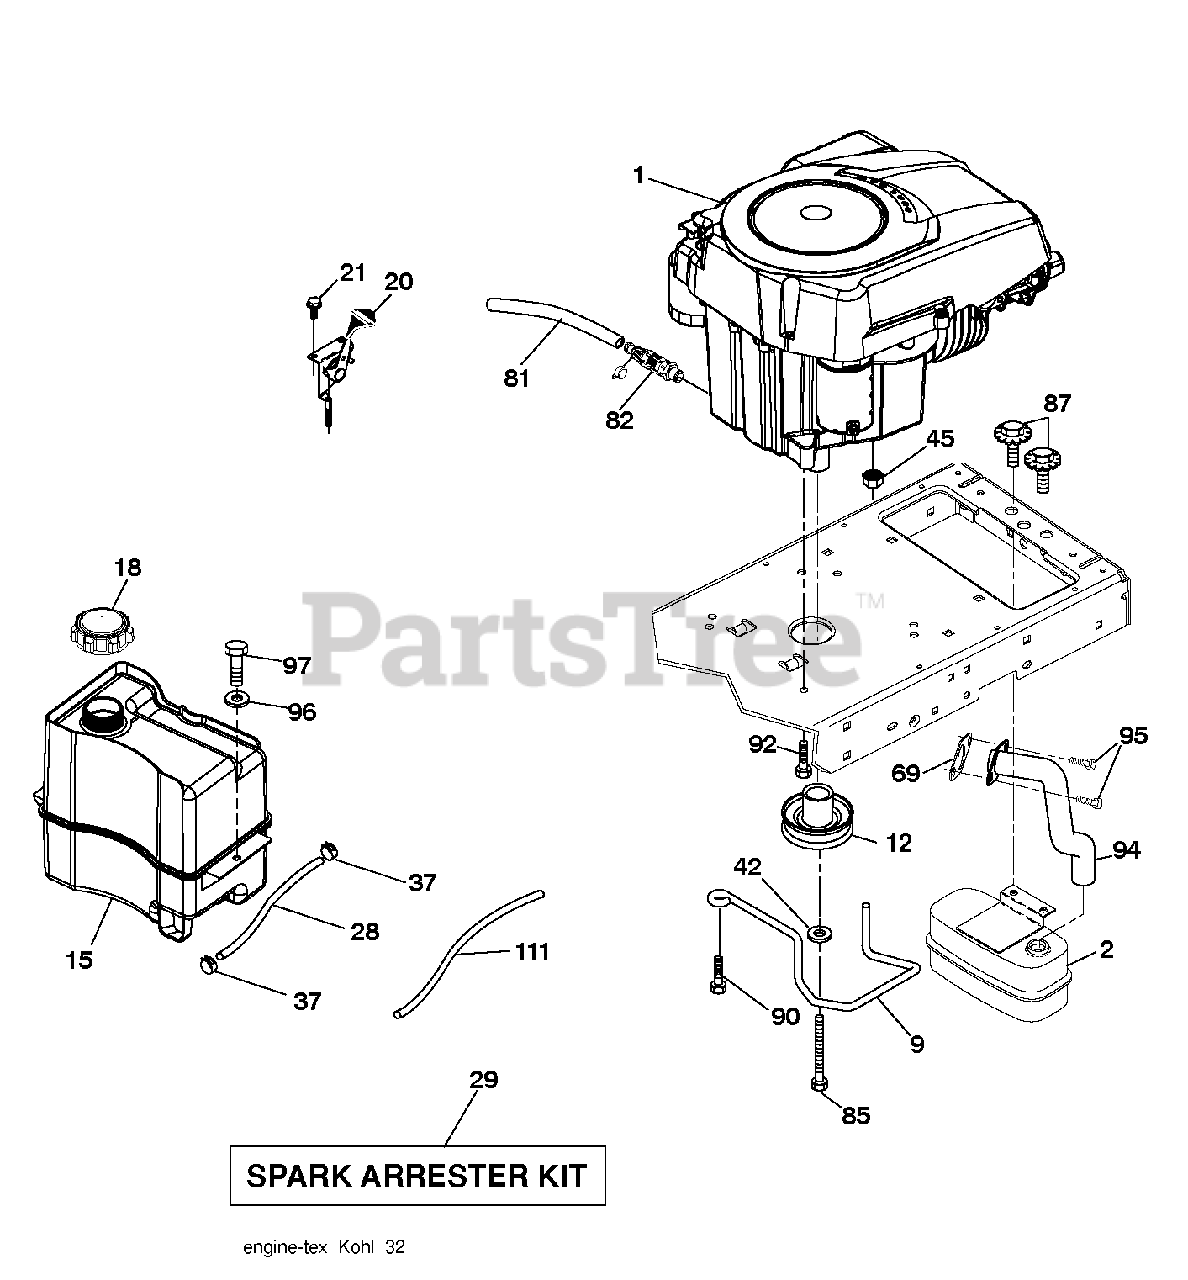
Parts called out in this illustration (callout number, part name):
1	Husqvarna TBD
2	MUFFLER.SINGLE.CYL.KOHL/B&S
9	KEEPER.BELT.ENGINE.4.2
12	PULLEY ENGINE
15	TANK.ASM.FRT.2.5 GAL.W/CAP.EPA
18	CAP.2.25'.VENTED.TETHER .EPA
20	CONTROL.TH/CK.COBRA.KO
21	SCREW.#10 X 0.750.BOS
28	LINE.FUEL.20"FRONT.EMI
29	KIT.SPARK ARRESTOR 794945 B&S
37	HOSE CLAMP
42	LOCKWASHER
45	NUT
69	GASKET.EXHAUST.KOHLER
81	TUBE, DRAIN OIL ASM.
82	VALUE.OIL.DRAIN
85	BOLT HEX 7/16-20X4-1/4"
87	Bolt, 5/16-18 X 1-3/4
90	SCREW 3/8-16X1
92	SCREW 3/8-16X1
94	RP.TUBE.EXHAUST.KOHL.COURAGE
95	SCREW.SOCKET HD.5/16-1
97	SCREW HEXWSHR 1/4-20X3/4
111	RP PURGE LINE
